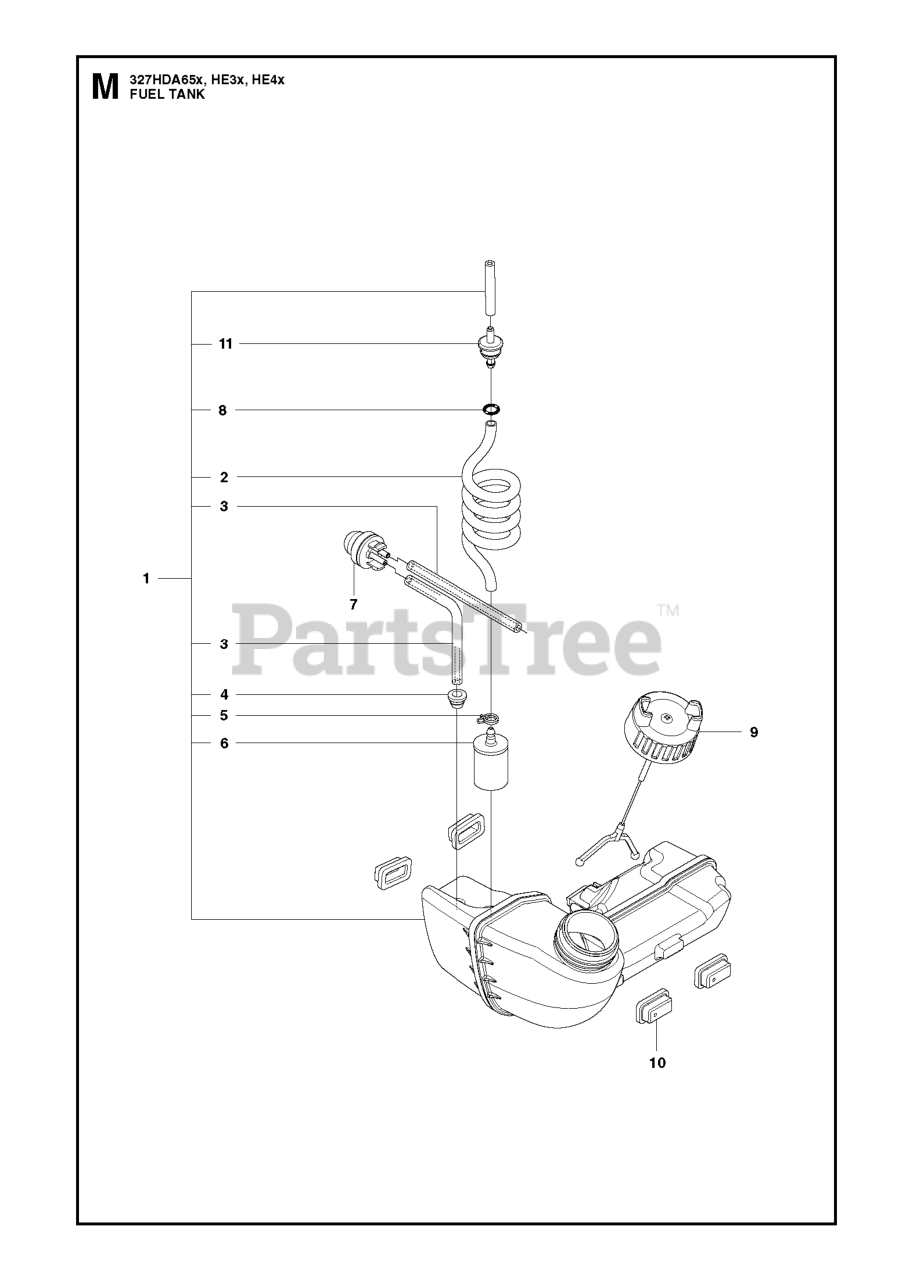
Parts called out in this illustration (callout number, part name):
1	FUEL TANK ASSY
3	HOSE.FUEL L=102
4	FUEL TANK BUSHING
5	HOSE CLAMP
6	RP FUEL FILTER
7	AIR PURGE BUBBLE
9	TANK CAP
11	HOSE NIPPLE
